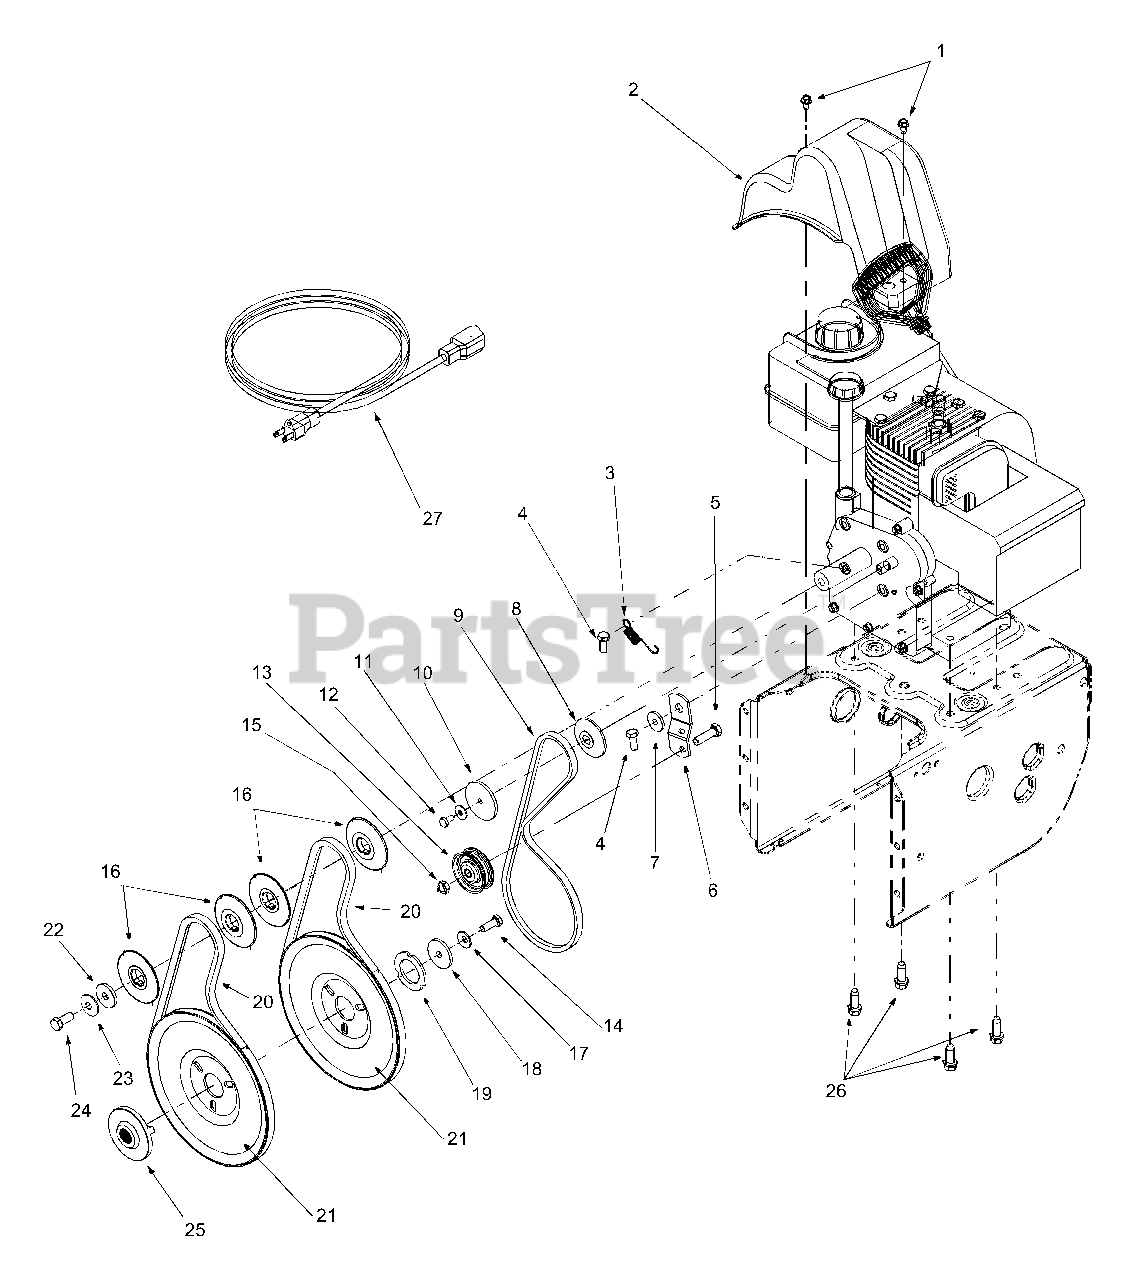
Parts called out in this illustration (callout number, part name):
1	Hex Washer Screw 1/4-20 x.625
2	Belt Cover
3	Extension Spring
4	Hex Screw 5/16-24 x .75
5	Hex Cap Screw 3/8-16 x 1.25
8	Pulley Half
9	V-Belt
10	Pulley Half
11	Bell Washer
12	Hex Cap Screw 1/4-28 x .50
13	Flat Idler
14	Lock Cap Screw 5/16-24 x .875
15	Lock Jam Nut 3/8-16
16	Pulley Half
17	Bell Washer
18	Flat Washer
20	Belt
21	Auger Pulley
22	Flat Washer
23	Bell Washer
24	Hex Cap Screw 3/8-24
25	Pulley
26	Hex Washer Screw 3/8-16 x 1.0
27	Extension Cord
